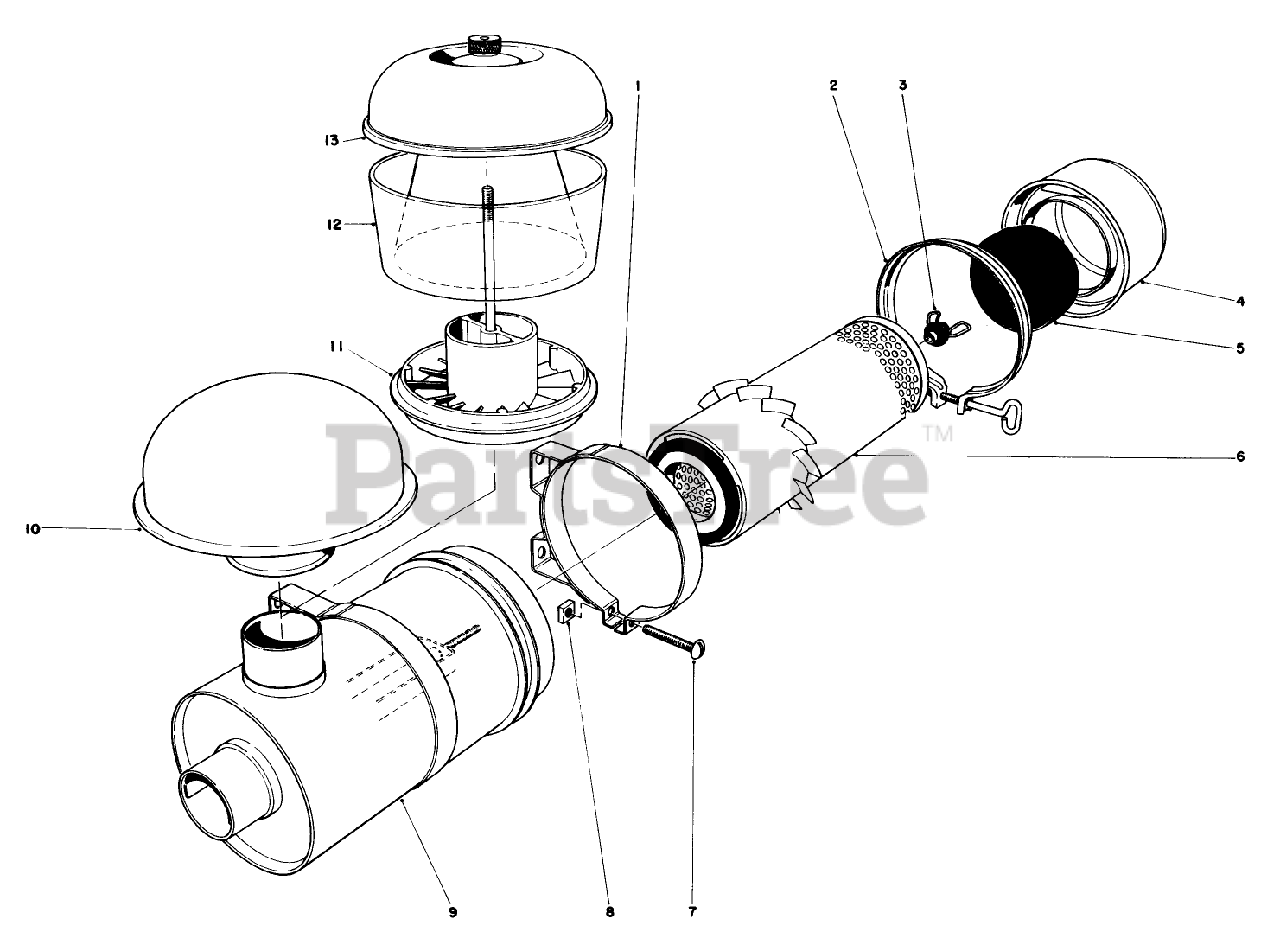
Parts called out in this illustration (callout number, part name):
1	MTG BAND ASM
2	CLAMP ASM
3	NUT ASM
4	CUP ASM
5	BAFFLE
6	ELEMENT ASM
7	SCREW
8	NUT-SQUARE
9	Body Assembly
10	HOOD-INLET, AIR
11	SLEEVE ASM
12	BOWL-CLEAR
13	COVER ASM
